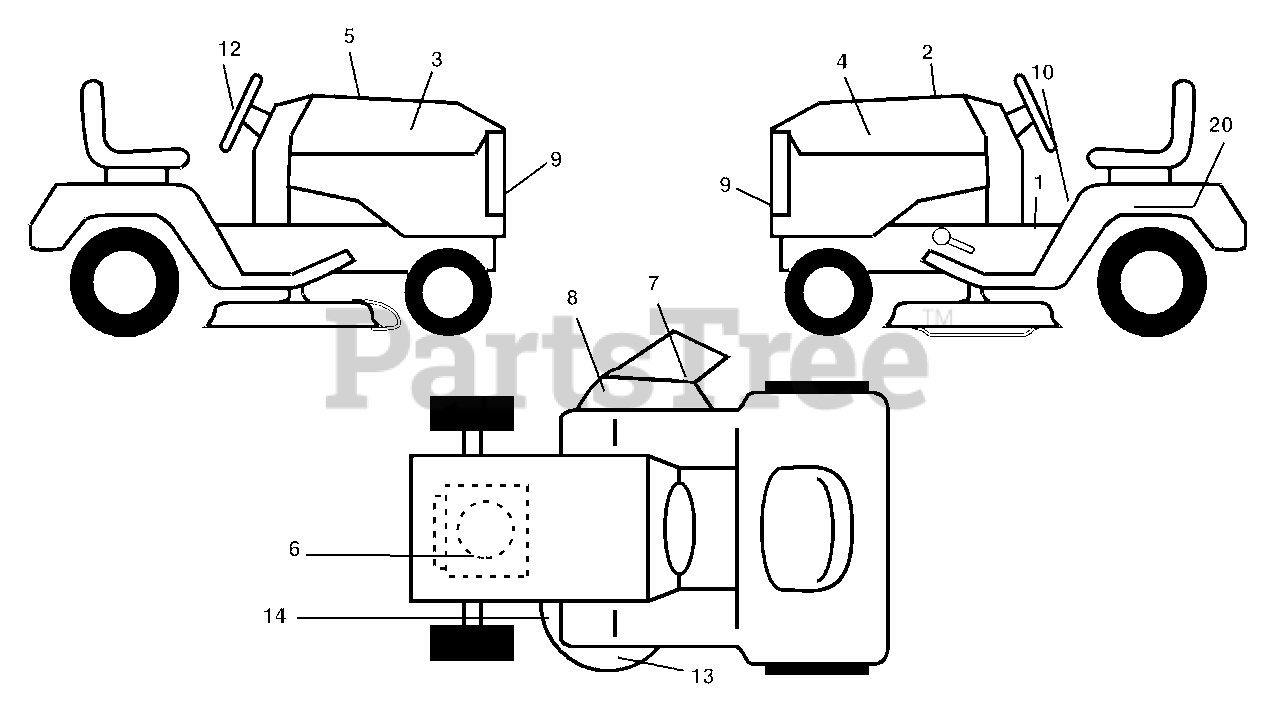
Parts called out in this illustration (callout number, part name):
1	Decal Oper.
2	Decal Replc Part
3	Decal Hood RH
4	Decal Hood LH
5	Decal Hood Cust.
6	Decal Engine
7	Decal Deck B 42
8	Decal Warning
9	Decal Side Panel
10	Decal Fender Danger Eng/Fr
12	Decal Steering Wheel
13	Decal Deck Heavy Duty
14	Decal V-Belt Schematic
20	Decal Bat Dan/Psn
